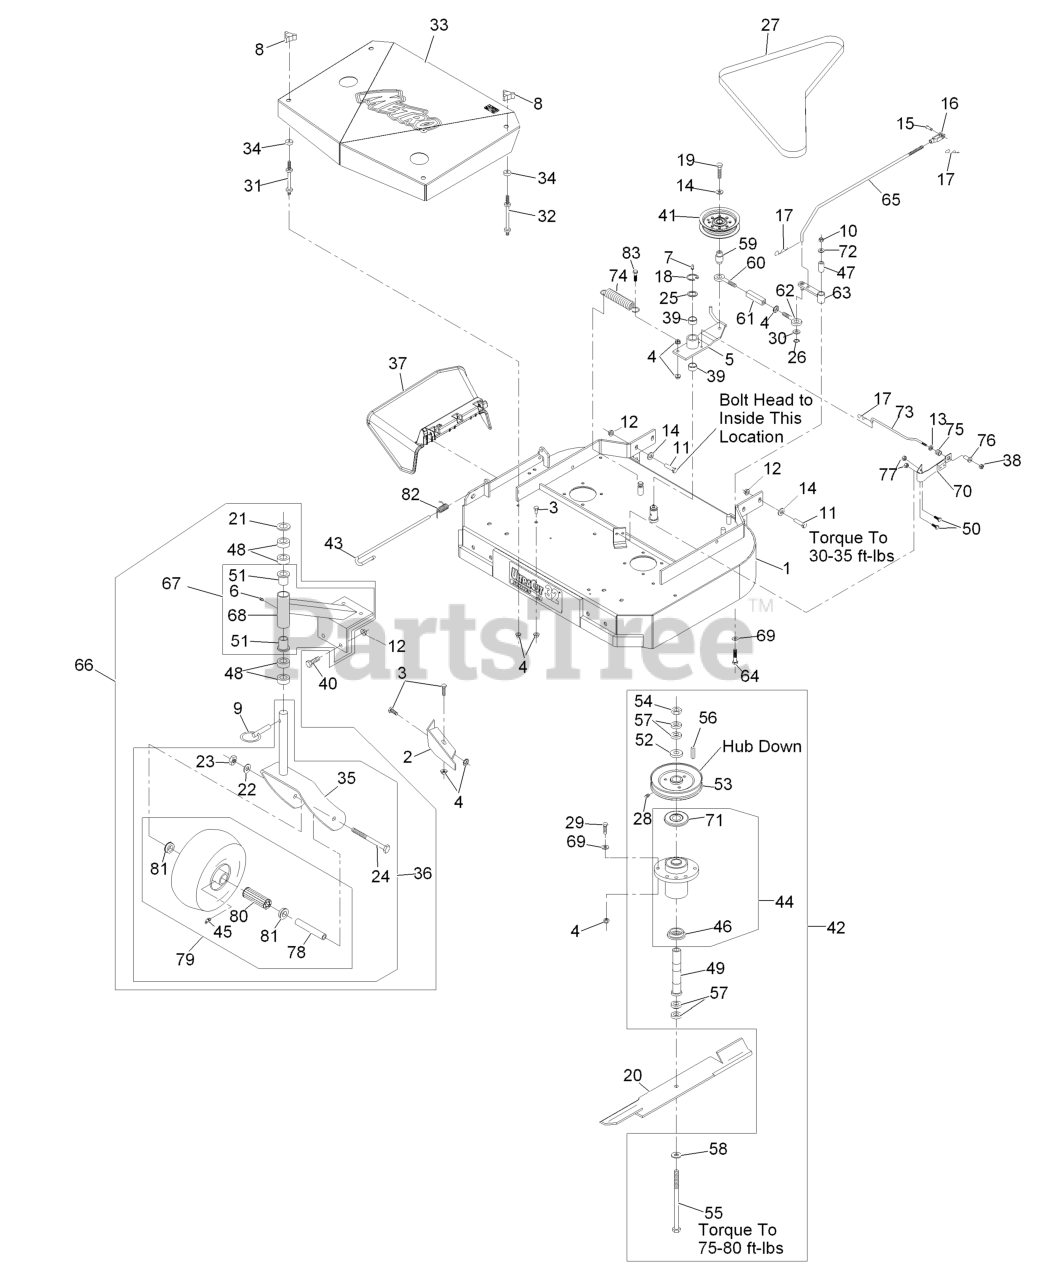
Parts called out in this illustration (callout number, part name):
1	Deck (116-0618-01) W/Decals & Dogleg & Discharge Deflector (32)
2	BAFFLE-DOGLEG
3	SCREW-HH
5	IDLER ARM ASM
6	FITTING-GREASE
7	FITTING-GREASE
8	KNOB-3 PRONG
10	NUT-LOCK, NI
11	SCREW-HH
12	NUT-HHF, WHIZ
13	RING-PUSH ON
14	WASHER-BELLEVILLE
15	PIN-CLEVIS
16	YOKE-ADJUSTABLE
17	PIN-COTTER
18	RING-RETAINING, EXT
19	SCREW-HH
21	WASHER-FLAT
22	WASHER-LOCK
23	NUT-HH
24	SCREW-HH
25	WASHER-SPINDLE
26	RING-RETAINING, EXT
27	BELT,BLADE METRO 32
28	SETSCREW
29	SCREW-HH
30	WASHER-PLAIN
31	STUD-SHIELD, BELT (SHORT)
32	STUD-SHIELD, BELT (LONG)
33	ASM,SHIELD W/DECALS 32 ME
36	ASM,CASTER/WHEEL
37	CHUTE DEFLECTOR XRK M056
38	NUT-LOCK, NI
39	SLEEVE-BEARING
40	SCREW-HH
42	ASM, CUTTER HOUSING OUTER
43	PIN-CHUTE
44	KIT, CUTTER HOUSING
45	FITTING-GREASE
46	SPACER-GUARD, BOTTOM
47	TUBE-PIVOT
48	SPACER-CASTER
49	TUBE-SPINDLE, SHORT
50	SCREW-HH
51	BEARING-FLANGED
52	WASHER-RETAINER, SHEAVE
54	NUT-HEX
55	SCREW-CAP, HH
58	WASHER-SPRING
59	BUSHING-ENGAGEMENT
60	EYEBOLT-THREAD, LH
61	BODY-TURNBUCKLE
62	EYEBOLT-THREAD, RH
63	ARM-ASSIST, 32/36
64	SCREW-HH
65	ARM-ASSIST, LINKAGE
66	ASM,CASTER/MOUNT
67	SUPPORT ASM
69	WASHER-SPRING
70	PAD AND SPRING ASM
71	GUARD-BEARING, TOP
72	WASHER-FLAT
73	ROD-BRAKE
74	SPRING-EXTENSION
75	SPRING-COMPRESSION
76	SPACER-FLANGED
77	NUT-LOCK, NI
79	KIT, SP CASTER WHEEL REPL
80	BEARING
81	BUSHING
82	SPRING, TORSION
83	SCREW-HH, SPECIAL
